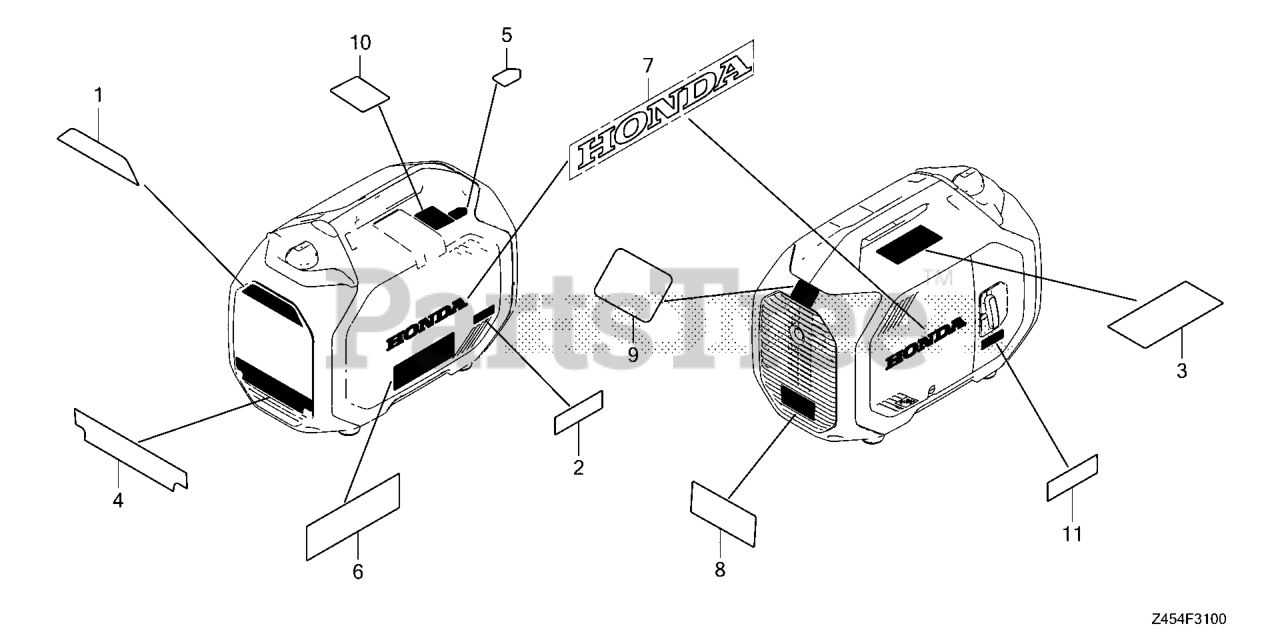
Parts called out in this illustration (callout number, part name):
1	MARK (EU3200I)
2	LABEL, WARNING
3	MARK, CO CAUTION
5	MARK, DIRECTION
7	MARK, HONDA
8	LABEL, EX. WARNING
9	MARK, EX. CAUTION
